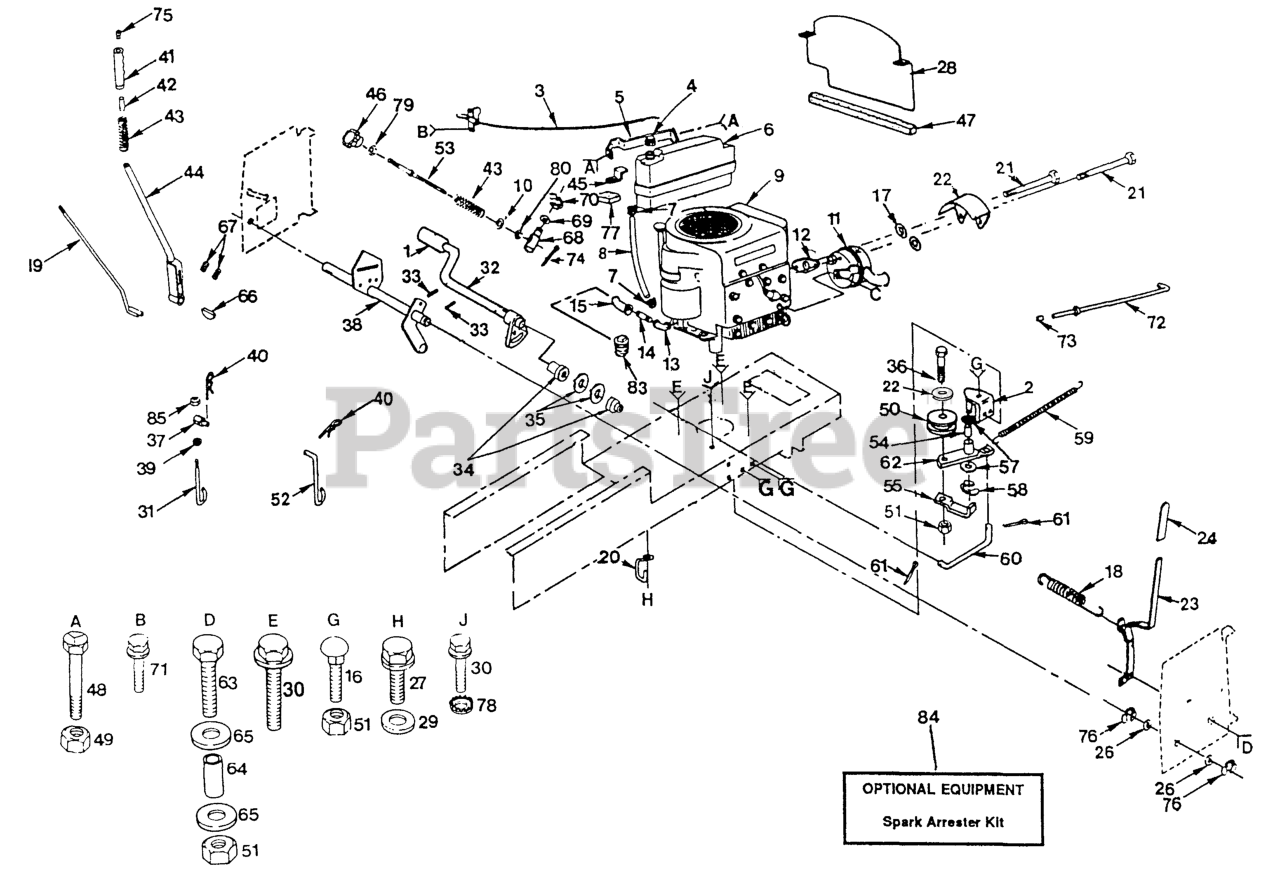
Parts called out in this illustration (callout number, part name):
1	PEDAL COVER T
3	CONTROL.THROTTLE
4	FUEL CAP LT
5	SUPT TANK FUEL
6	FUEL TANK NLA
7	HOSE CLAMP
8	HOSE T
9	Engine Briggs & Stratton, Type No. 0412-01
12	GASKET ENGINE
13	STREET ELBOW LT
14	Std. Pipe Nipple 3/8 - 18 NPT x 3 1/2
15	ELBOW
16	Bolt, Carriage 3/8 - 16 x 3/4
17	WASHER
18	SPRING.EXT.8.5"
19	ROD ASS'Y LEVER
20	KEEPER BELT ENGLH
22	HEAT SHIELD
24	GRIP-HANDLE T
25	WASHER
26	Washer 29/32 x 1 - 1/4 x 16 Ga.
27	SCREW
28	BAFFLE,VERTICAL NLA
29	WASHER
30	SCREW
31	LINK ADJ T
32	SHAFT FOOT PEDAL
33	PIN.ROLL.3/16 X 1"
34	BEARING.NYLON
35	WASHER LT
37	TRUNNION T
39	NUT **
40	RETAINER-SPRNG RB
42	PLUNGER BUT KIT
43	SPRING**
44	LEVER LIFT
45	BRACE-TANK LT
46	HDLE ADJ LIFT
47	FOAM-STRIP LT
48	BOLT.FIN.HEX.5/16-18X3/4
49	LOCKNUT
50	IDLER PULLEY
52	LIFT LINK LT
53	ROD LIFT LT
54	BEARING LT (2 2)
55	RETAIN BELT
59	SPRING, RETURN LT
60	LINK, CLUTCH LT
61	COTTER PIN
63	BOLT
64	BUSHING YT
65	Washer 3/8 x 1 x 12 Ga.
68	TRUNION LT
69	Washer 15/32 x 3/4 x 16 Ga.
71	SCREW LT
72	ROD BRAKE PARK
73	PLUNGER CAP
74	COTTER PIN
75	PLUNGER BUT KIT
77	PAD-SPACER T
78	LOCKWASHER
79	NUT
80	NUT T
84	SPARK ARREST
85	NUT LOCK YTH
